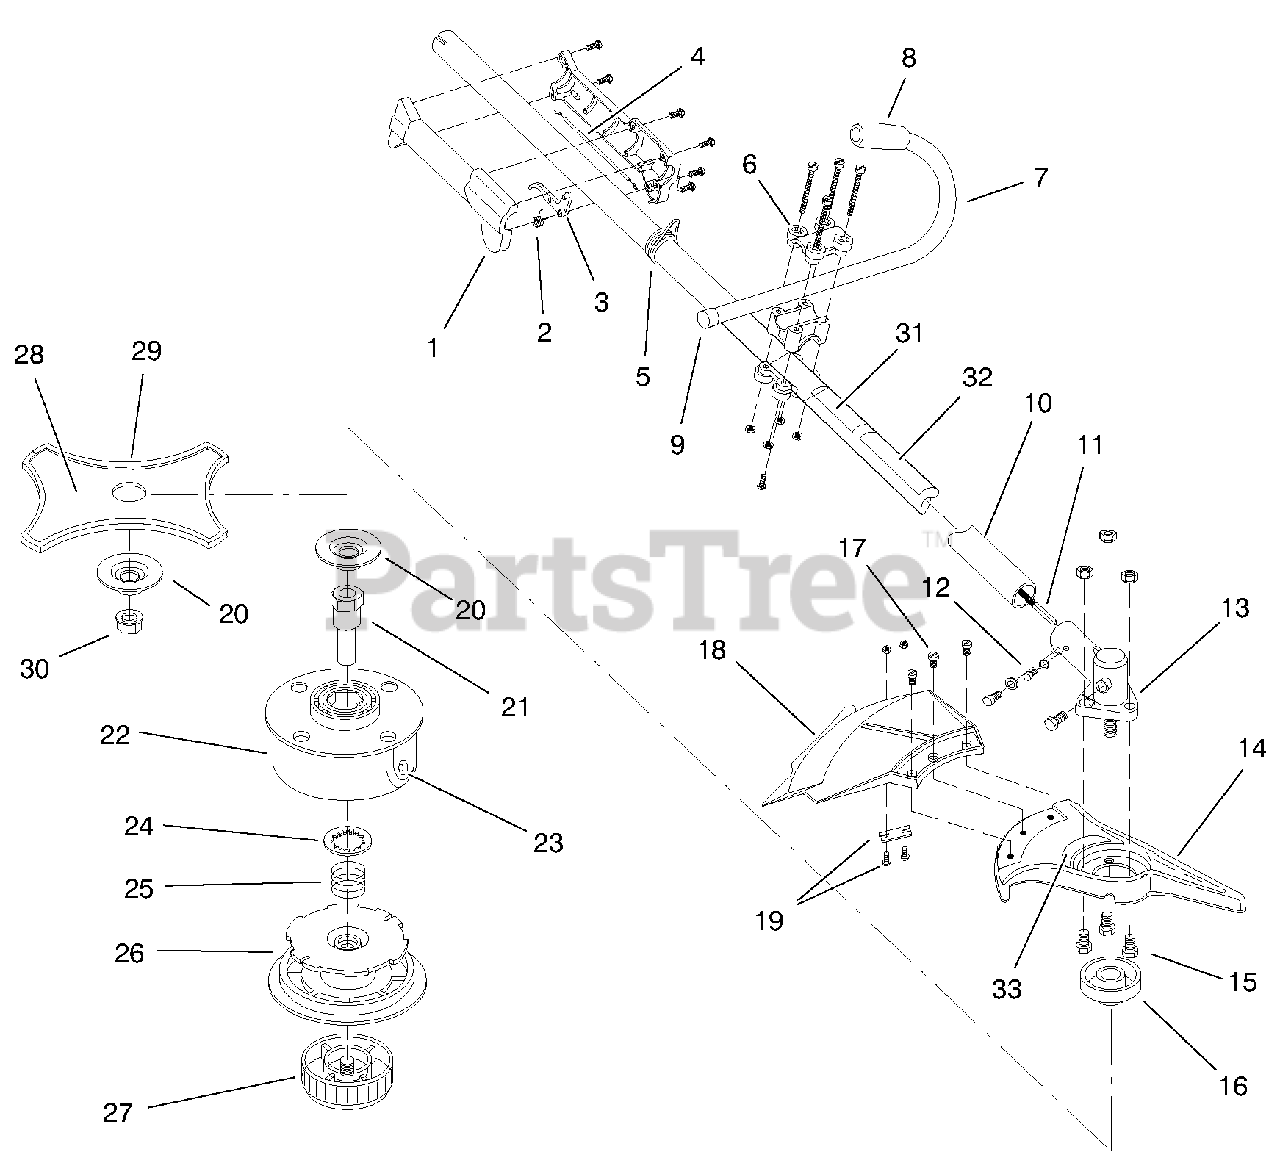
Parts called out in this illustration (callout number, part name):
1	Throttle Housing & Trigger ASM
2	Spring-Throttle Trigger
3	Throttle Trigger
4	Throttle Cable ASM
5	Support-Shoulder Harness
6	Handle Bracket ASM
7	J-Handle ASM (Includes Ref #8 & 9)
9	Tube Closure
10	Housing-Drive Shaft
11	Flexible Drive Shaft
12	Mounting Hardware & Grease Plug ASM
13	Gearbox ASM (Incl. Ref #12, 15, 16, 30)
14	Shield Mount
15	Screw-Shield Mounting
16	Blade Driver
17	Screw-Shield Mounting
18	Shield & Blade ASM (Includes Ref #19)
19	Blade ASM
20	Washer-Retaining
21	Spool Shaft
22	Outer Spool & Eyelet
24	Retainer
26	Inner Reel
27	Bump Knob ASM
28	Blade
29	Blade Cover
30	Nut-Lock
31	Decal-Safety Symbols
32	Decal-Safety
33	Decal-Warning, Blade
